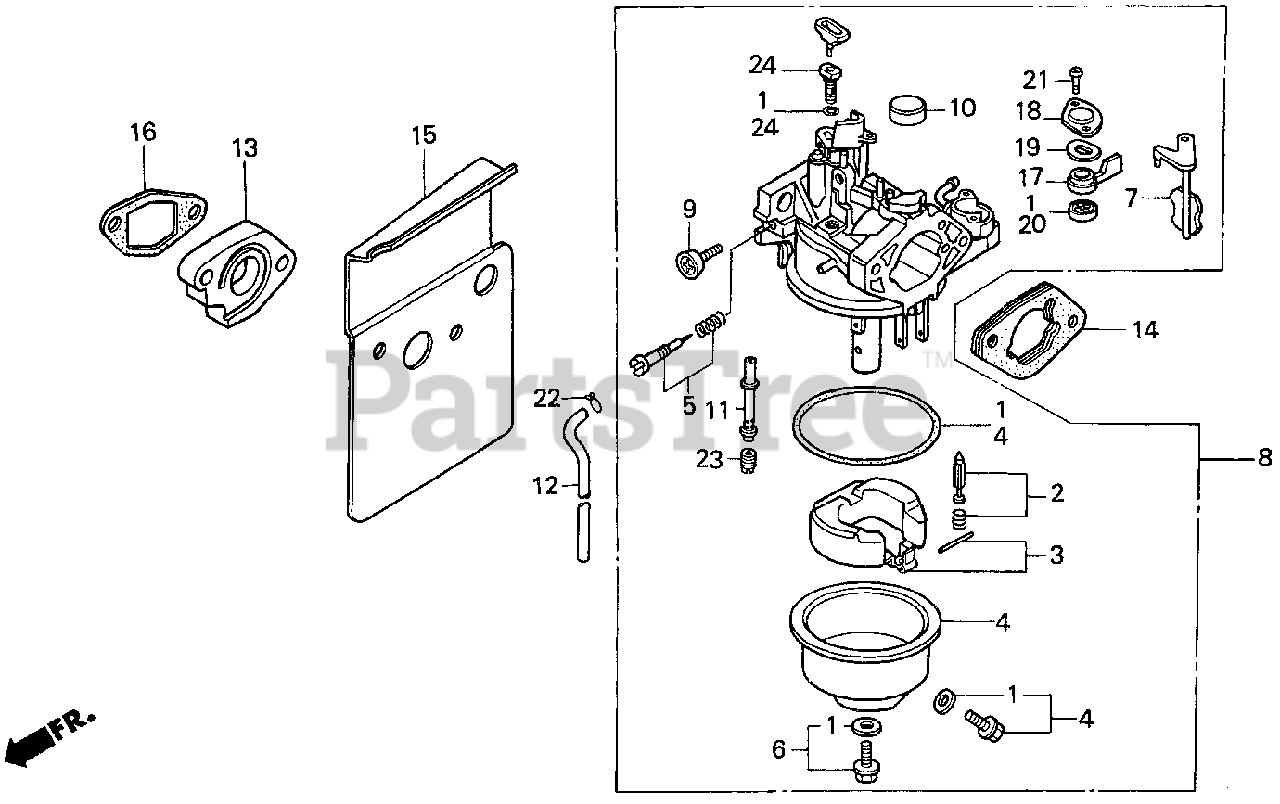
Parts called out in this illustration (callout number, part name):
1	GASKET SET
2	VALVE SET, FLOAT
3	FLOAT SET
4	CHAMBER SET, FLOAT
5	SCREW SET, PILOT
6	SCREW SET B
7	CHOKE SET
8	CARBURETOR ASSY. (BE23A C)
8	CARBURETOR ASSY.
9	SCREW, THROTTLE STOP
10	CAP, CHOKE LEVER DUST
11	NOZZLE, MAIN
12	TUBE, AIR VENT (75MM)
13	INSULATOR, CARBURETOR
14	SPACER, CARBURETOR
15	GASKET, CARBURETOR
16	GASKET, INSULATOR (Honda Code 2090074). (NOT AVAILABLE)
17	LEVER, VALVE
18	PLATE, LEVER SETTING
19	SPRING, VALVE LEVER
20	GASKET, VALVE
21	SCREW, PAN (3X8)
22	CLIP, TUBE (B8)
23	JET, MAIN (#80)
23	JET, MAIN (#82)
23	JET, MAIN (#85)
24	JET SET, PILOT (#45)
